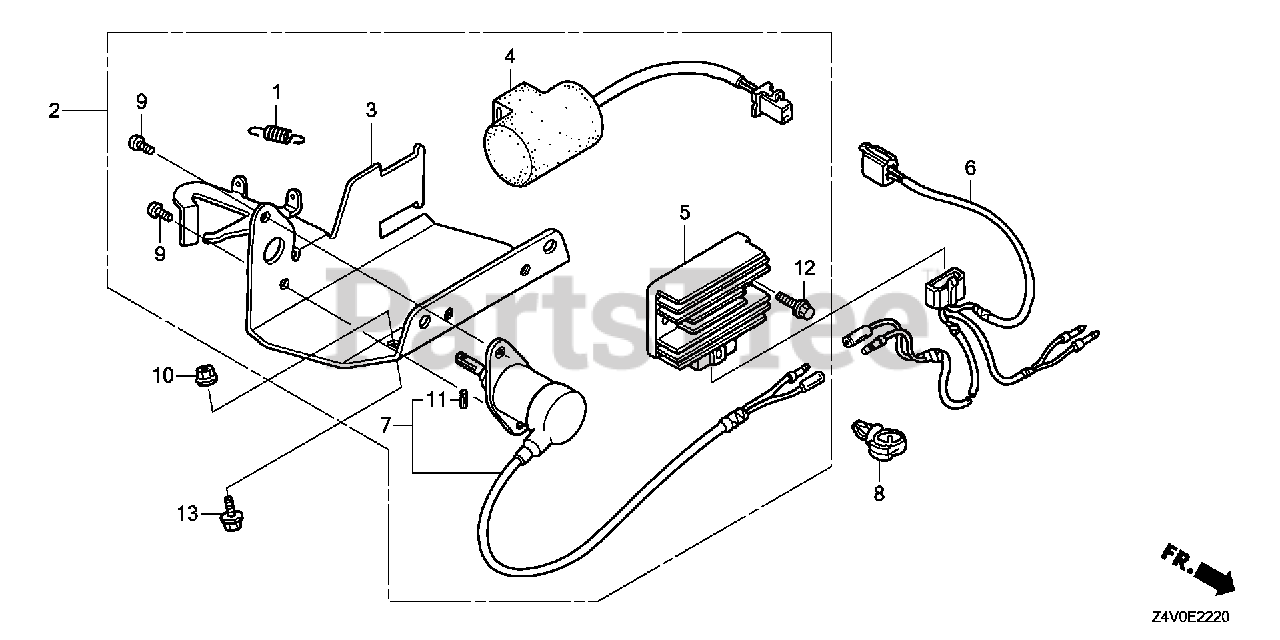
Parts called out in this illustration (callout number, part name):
1	SPRING, CHOKE RETURN
2	THROTTLE ASSY., AUTO
3	LEVER, SOLENOID THROTTLE
4	CONDENSER UNIT
5	RECTIFIER ASSY., REGULATOR
6	SUB-HARNESS ASSY.
7	SOLENOID ASSY., AUTO THROTTLE
8	CLIP, WIRE HARNESS (25MM)
9	SCREW, PAN (5X8)
10	NUT, FLANGE (6MM)
11	PIN, SPRING (2.5X16)
12	BOLT, FLANGE (6X16) Use from Engine SN 2056820.
13	BOLT, FLANGE (6X25)
13	BOLT, FLANGE (6X28)
